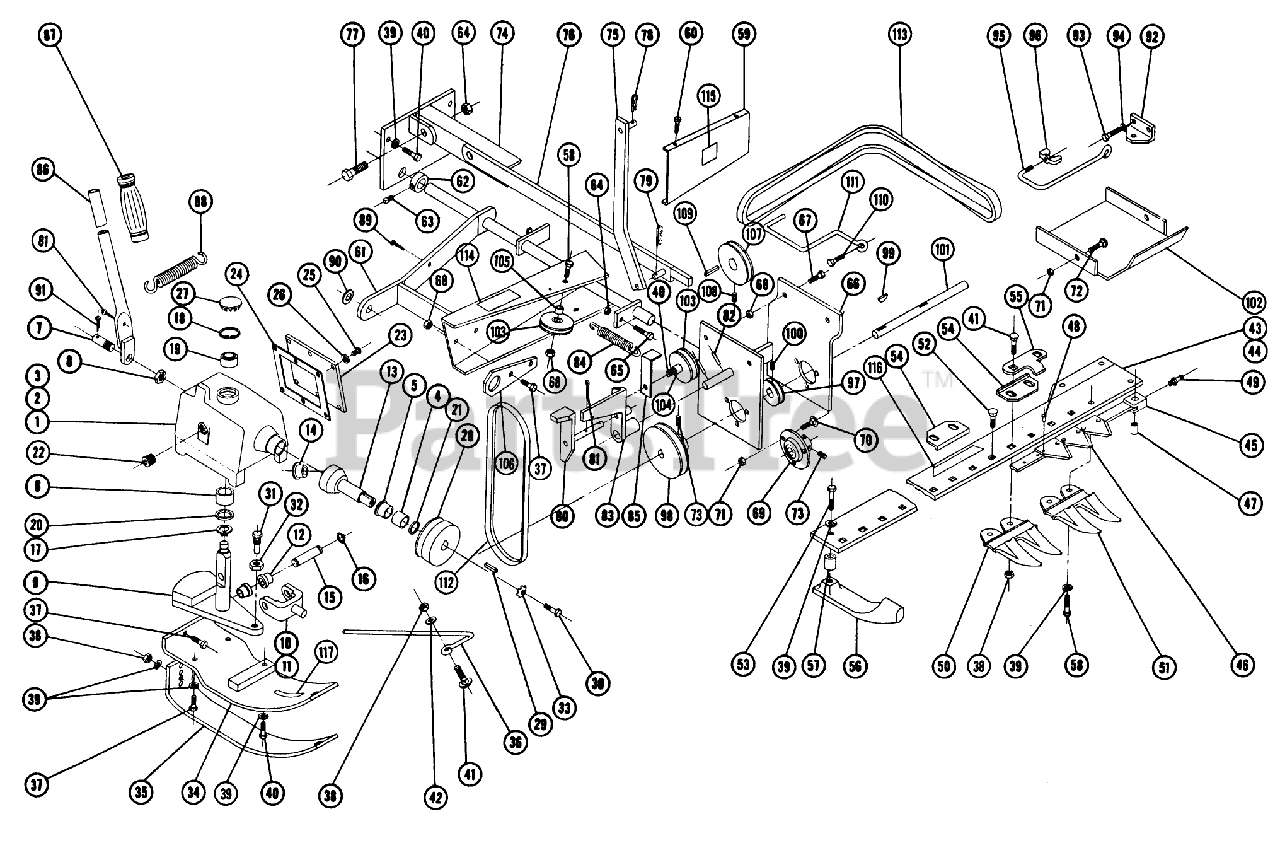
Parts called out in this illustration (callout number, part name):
1	Ass-y Housing Complete-Sickle Drive
2	Ass-y Housings & Bearings
3	Housing
4	Bearing-Bronze Sleeve
5	Bearing-Bronze Sleeve
6	Bearing-Bronze Sleeve
7	Pin
8	Nut, 3/4-16
9	Ass-y. Shaft-Weldment
10	Ass-y. Yoke
11	Yoke
12	Bearing-Bronze Sleeve
13	Ass-y. Shaft & Bearing
14	Bearing-Bronze Sleeve
15	Pin Yoke
16	SNAP RING- 5/8 EXT
17	SNAP RING
18	Ring-Snap
19	Bearing-Ball
20	Seal 1 1/4 I.D.
21	Seal
22	Plug 1 x 11 1/2 NPTF
23	Cover Plate
24	Gasket
26	Lockwasher #10
27	Plug Button
28	Pulley 4 Dia.
29	KEY-STRAIGHT
30	Bolt 3/8-16 x 7/8
31	Pin Sickle Drive
32	Nut-5/8-18
33	WASHER
34	Ass y. Shoe-Upper-Weldment
35	Shoe-Lower
36	Rod-Grass
37	Bolt 3/8-16 x 1
39	Lockwasher
40	Bolt, 3/8-16 x 1/2
41	Bolt Carriage 3/8-16 x 1
42	Washer
43	Ass-y. Cutter Bar Complete
44	Ass-y. Bar Guard
45	Ass-y. Knife Bar & Sections
46	Section
47	Bushing
48	Rivet
49	ZERK 90DEGREE
50	Twin Guard
51	Guard Cutter Bar
52	Bolt 3/8-16 x 1
53	Bolt, 3/8 16 x 2
54	Wear Plates
55	Clip, Hold Down
56	Skid
57	Spacer
58	Bolt 3/8-16 x 1
59	Cover Belt
60	Screw Hex Self Tap #8-32 x 3/8
61	Ass-y. Frame
62	Collar
64	Locknut-1/2-13
66	Ass-y. Shaft Support
68	3/8-16 E.S.
69	Bearing-Flanged
70	Bolt Hex 5/16-18 x 3/4
71	Nut-Nylok
72	Bolt-Car. 5/16-18 x 1
73	Set Screw 5/16-18 x 5/16
74	Ass-y. Plate - Mounting
75	Ass-y. Bar - Lift
76	Ass-y. Bar and Pin - Lower
77	Bolt Hex 1/2-13 x 1 1/2
78	Hairpin
79	Hairpin
80	Ass-y. Lever
81	Cotter Pin
82	Roll Pin
83	Pedal
84	Spring
85	BRACKET GUARD
86	Ass-y. Lever Lift
87	Grip
88	Spring
89	Cotter Pin 3/16 x 1
91	Cotter Pin 1/8 x 1/3
92	Bracket-Travel Hook
93	Bolt 5/16-18 x
94	Lockwasher
95	Hook - Travel Support
96	3/8 NC Wing Nut
97	Pulley
98	Pulley
99	Key
100	Set Screw 1/4-20 x 1/4
101	Shaft
102	Shield - Pulley
103	Pulley
105	SPACER
106	Link
107	Puller-Engine-Drive
109	Key
110	Bolt Hex. 7/16-4 x 1 1/4
112	Belt "A" Sec. 37"
113	V BELT
114	Decal-Caution
115	Decal
116	Decal
117	Decal
